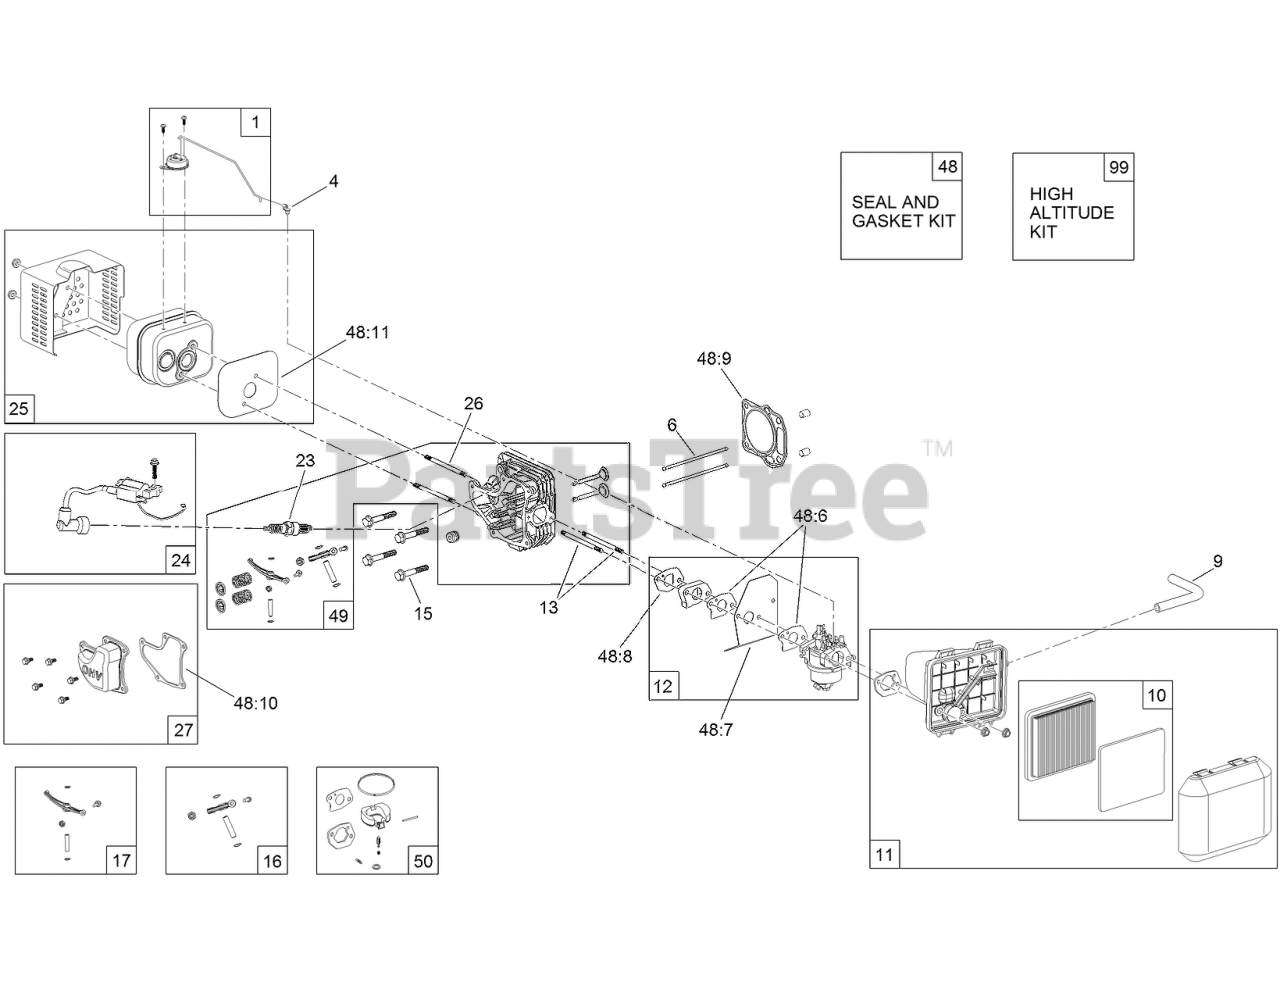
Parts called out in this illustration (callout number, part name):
1	THERMAL CONTROL KIT
4	LOCK-THROTTLE
6	ROD-PUSH
9	TUBE-BREATHER
10	AIR FILTER AND PREFILTER KIT
11	AIR CLEANER ASM KIT
12	CARB REPLACEMENT KIT
13	STUD-INTAKE
15	BOLT-FLANGE
16	INTAKE ROCKER ARM ASM
17	EXHAUST ROCKER ARM ASM
23	SPARK PLUG
24	IGNITION ASM
25	MUFFLER AND SHIELD KIT
26	STUD-EXHAUST
27	VALVE COVER KIT
48	SEAL AND GASKET KIT
48:6	GASKET-CARBURETOR
48:7	INSULATOR-CARBURETOR
48:8	GASKET-INTAKE
48:9	GASKET-HEAD
48:10	GASKET-VALVE COVER
48:11	GASKET-EXHAUST
49	COMPLETE HEAD ASM
50	INTERNAL CARB KIT WITH GASKETS
99	HIGH ALTITUDE KIT
